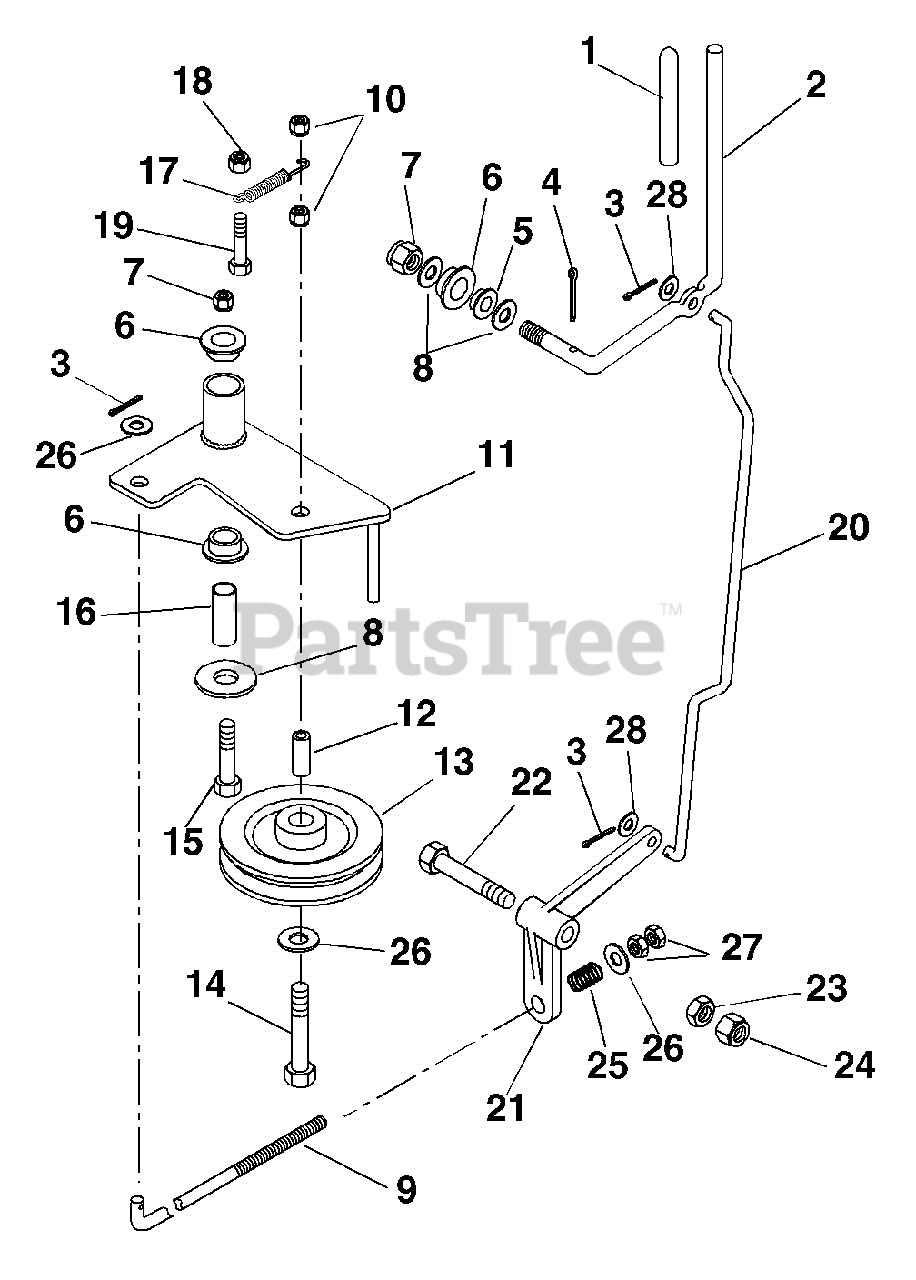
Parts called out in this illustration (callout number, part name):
1	Grip PTO Lever
2	Lever-PTO Actuating
3	Pin-Cotter .09X1.00
4	Pin-Cotter .18 x 1.50
5	Bushing-Flange-Nylon .515 x .750 x .745 x 1.00
6	Bushing-Flange-Nylon .762 x 1.0 x .580 x 1.48
7	Nut-Locking-Center .50-13
8	Washer-Flat-Steel .50 x 1.25 x .083
9	Rod, PTO Link-Pro 150
10	Nut-Locking-Center .38-16
11	Declutch Arm- Pro PTO
12	Spacer .391 x .75 x 1.25
13	Idler-Pulley Flat 3.25 x .625
14	Bolt-Hex .38-16 x 3.50 Grade 5
15	Bolt-Hex .50-13 x 3.25 Grade 5
16	Bushing, Declutch Arm Pivot
17	Spring-Tension .095 x .85 x 4.38
18	Nut-Locking-Center .31-18
19	Bolt-Hex .31-18 x 1.25 Grade 5
20	Rod, PTO Lever Link-Pro 150
21	Lever, PTO Clutch
22	Bolt-Hex .50-13X2.50 Grade 5
23	Nut-Hex .50-13
24	Nut-Locking-Center .50-13
25	Spring-Compression .125 x .78 x 1.00
26	Washer-Flat-Steel .406 x .812 x .065
27	Nut-Hex .38-16
28	Washer-Flat-Steel .344 x .688 x .065
